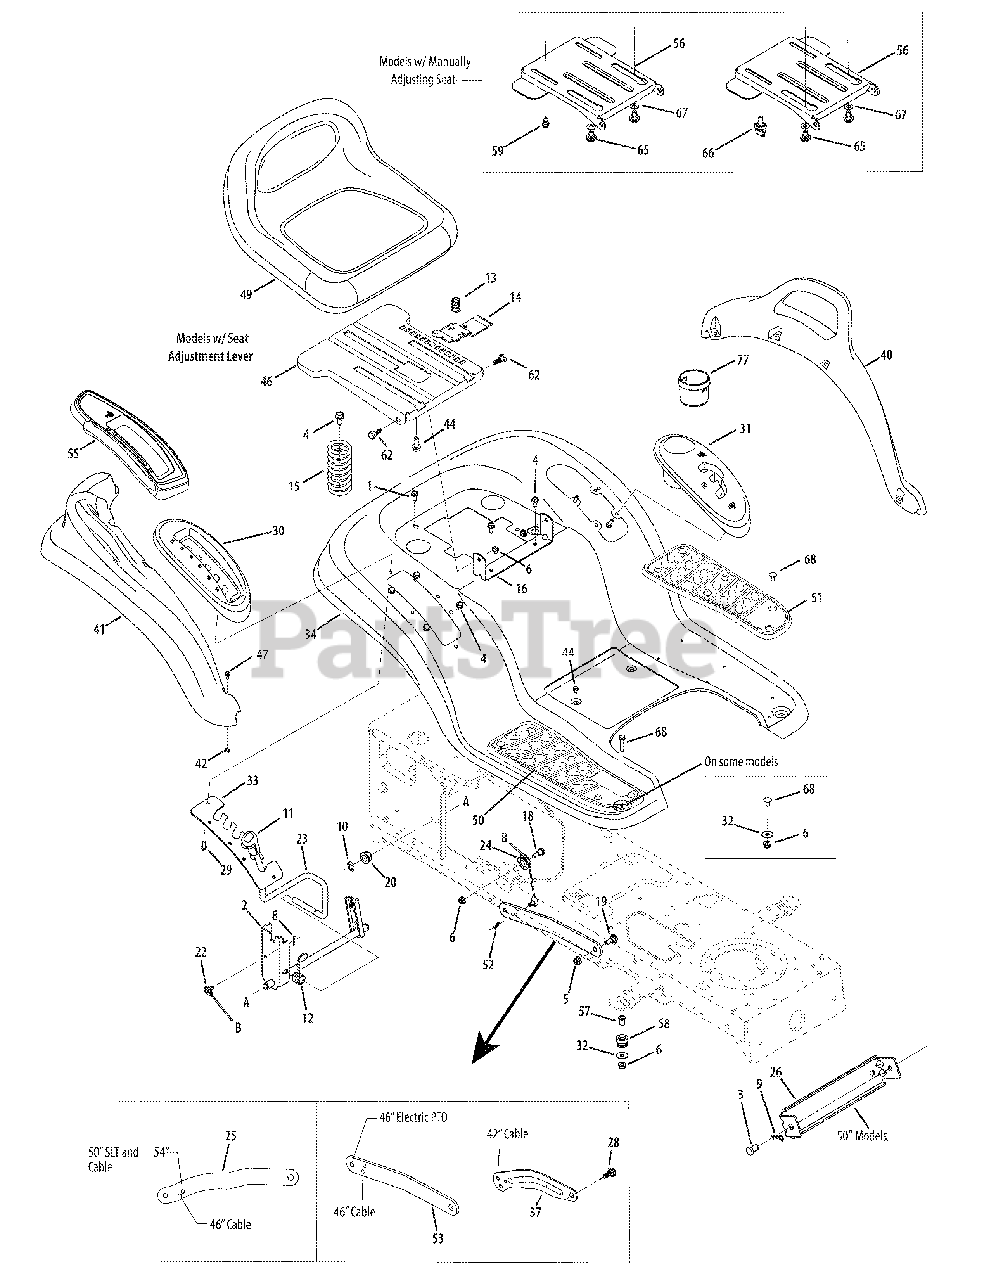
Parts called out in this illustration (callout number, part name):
2	Lift Shaft Assembly
4	S-Tapp Scr 5/16-18 x .75
5	Hex Flange Locknut 3/8-16 Gr. F,Nylon
6	Hex Flange Locknut 5/16-18 Gr. F Nylon
8	Int. Cotter Pin 5/16 Dia.
9	Internal Cotter Pin .080 x 1.5625
12	Torsion Spring
13	Spring, Compression Seat Adj Levr
14	Lever, Seat Adjust
15	Spring, Compression Seat
18	Shoulder Scr. .437 Dia x .47
19	Shoulder Screw .500 x .25 (46"/50")
20	Hex Flange Bearing .630 ID
22	Lift Cable, 16.16
24	Roller Pulley
25	Arm Lift
26	Deck Stabilizer Bracket
28	Shoulder Screw .625 x .175: 3/8-16
29	Hex Scr. 1/4-15 x .75
30	Lift Lever Cover
31	Shift Lever Cover w/Cup Holder
32	Flat Washer .344 ID x 1.0
33	Lift Adjustment Bracket
37	Deck Lift Arm RH (42" Deck)
40	LH Fender Flare
41	RH Fender Flare
42	Sems Hex Nut 1/4-20
44	Hex Wash S-Tapp Scr 1/4-20 x .50
46	Seat Mount Bracket
47	Carriage Bolt 1/4-20 x 1.00" Lg.
49	High Back Seat Black
52	Cotter Pin 3/32 dia. x 1.00 Lg.
53	Arm Lift (46" deck w/manual PTO & 50" deck)
55	Lift Lever Cover (Model 60R)
56	Seat Pivot Bracket, Manually Adjusted
58	Flg. Spacer .3125 x .4375 x .625
59	Hex Wash Hd Scr. 3/8-16 x .625 Gr. 5
62	Shoulder Bolt .437 Dia. x .268
65	Shoulder Spacer .625 x .175, 3/8-16
66	Knob, 3/8-16 x .625
67	Flat Washer .406 x .875 x .059
68	Carriage Bolt 5/16 x 18 x .75" Lg.
